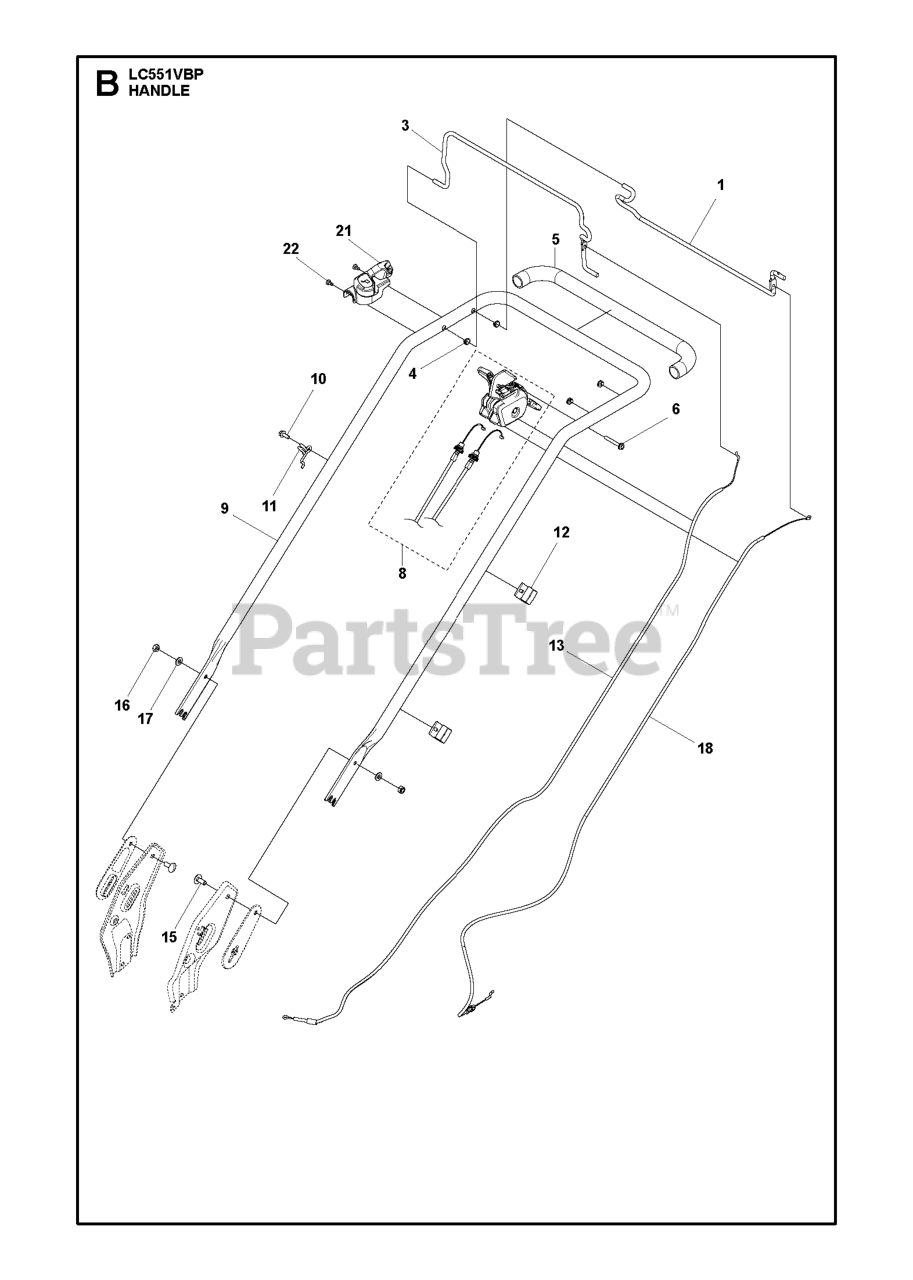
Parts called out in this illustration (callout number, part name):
10	SCREW
16	LOCKNUT M8
17	WASHER BRB 8.4X17
22	SCREW ITXPANTT M5X10 ZPB (A00
